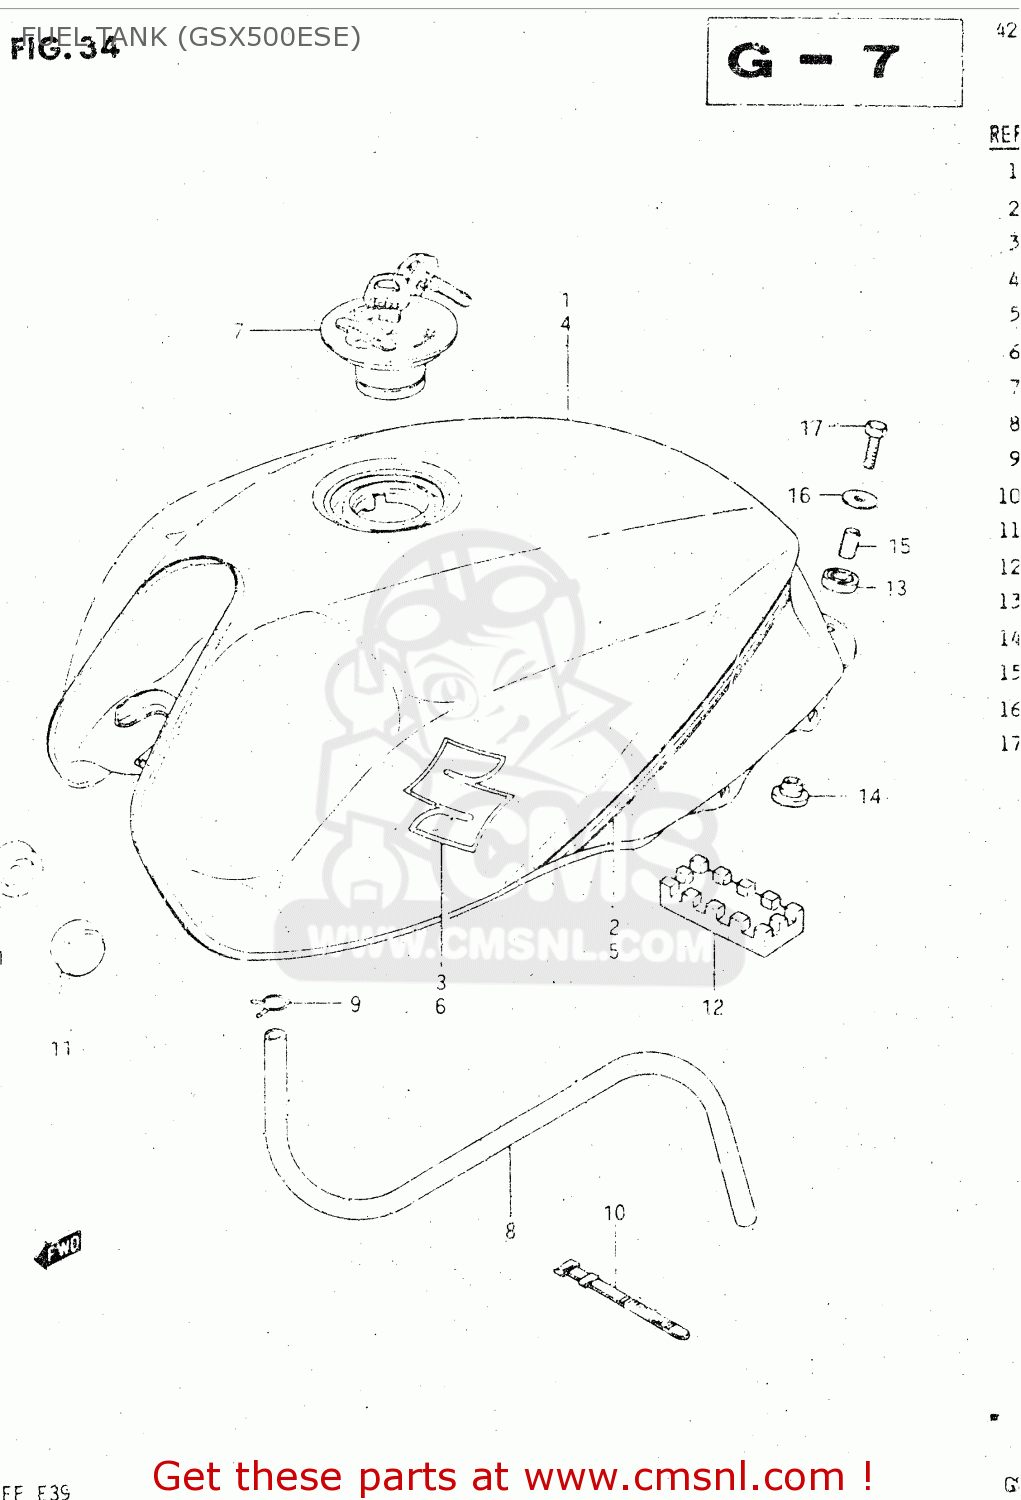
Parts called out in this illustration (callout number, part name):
1	TANK ASSEMBLY,FUEL
2	TAPE SET,FUEL TANK
3	EMBLEM
4	TANK ASSY, FUEL
5	TAPE SET, FUEL TANK
6	EMBLEM
7	CAP ASSY,FUEL TANK
8	HOSE,FUEL
9	CLIP
10	CLAMP(L:187)
11	CUSHION
12	CUSHION,FUEL TANK
13	CUSHION
14	CUSHION
15	SPACER (6.4X9X20)
16	WASHER (6.5X24X1.6)
17	BOLT
